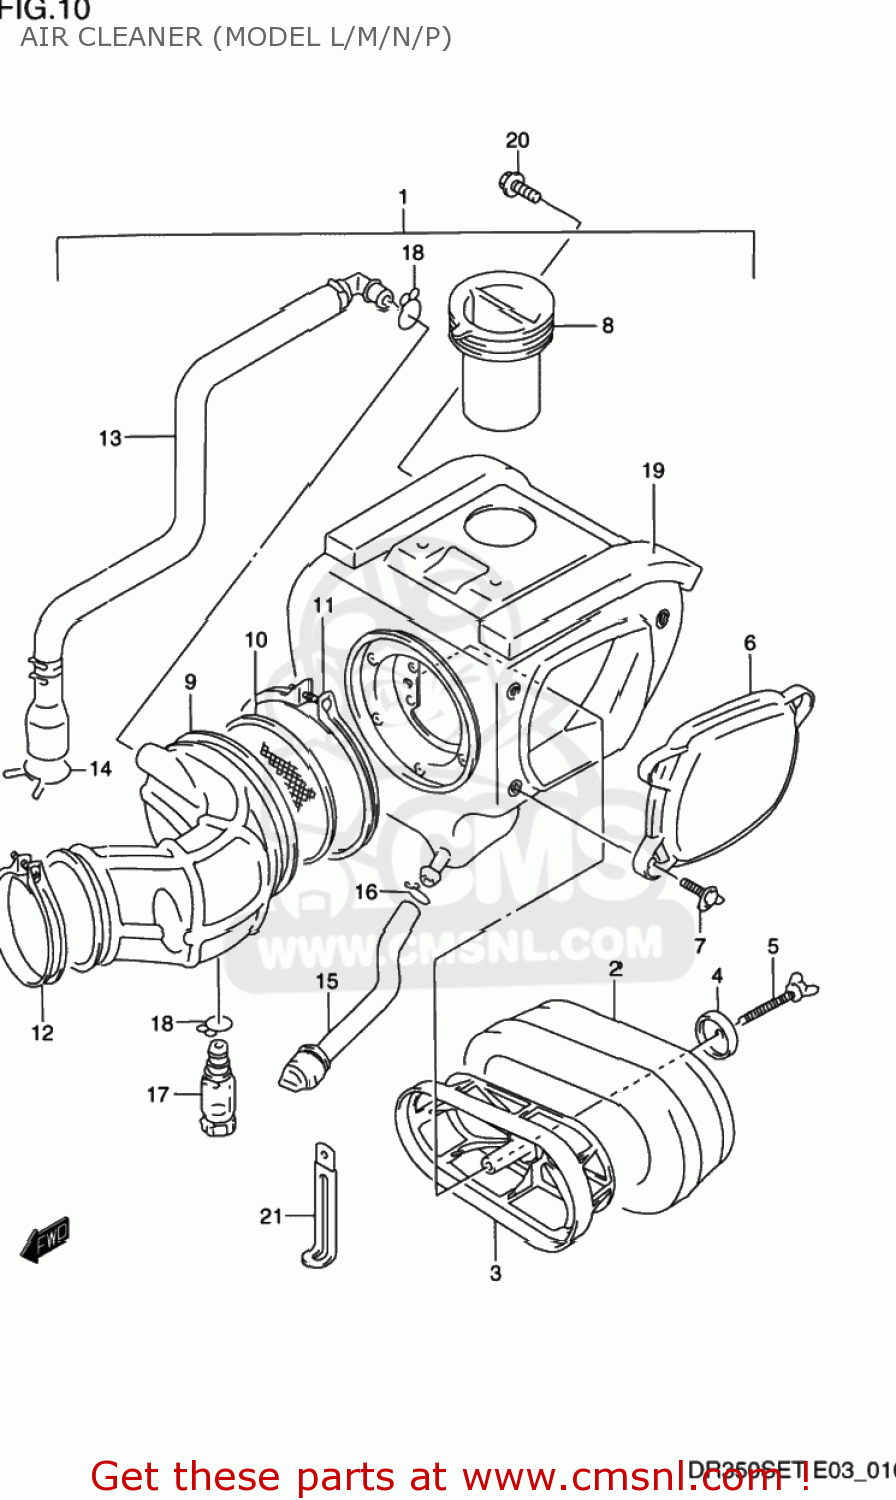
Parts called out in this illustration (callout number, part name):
1	CLEANER ASSEMBLY,AIR
2	FILTER
3	HOLDER,FILTER
4	WASHER,AIR CLEANER
5	BOLT,WING
6	CAP,AIR CLEANER
7	BOLT,WING
8	TUBE,INLET
9	TUBE,OUTLET
10	TRAP,FRAME
11	CLAMP
12	CLAMP
13	TUBE,BREATHER
14	CLIP
15	DRAIN TUBE
16	CLIP
17	TUBE,DRAIN B
18	CLIP
19	CUSHION
20	BOLT
21	CLAMP
